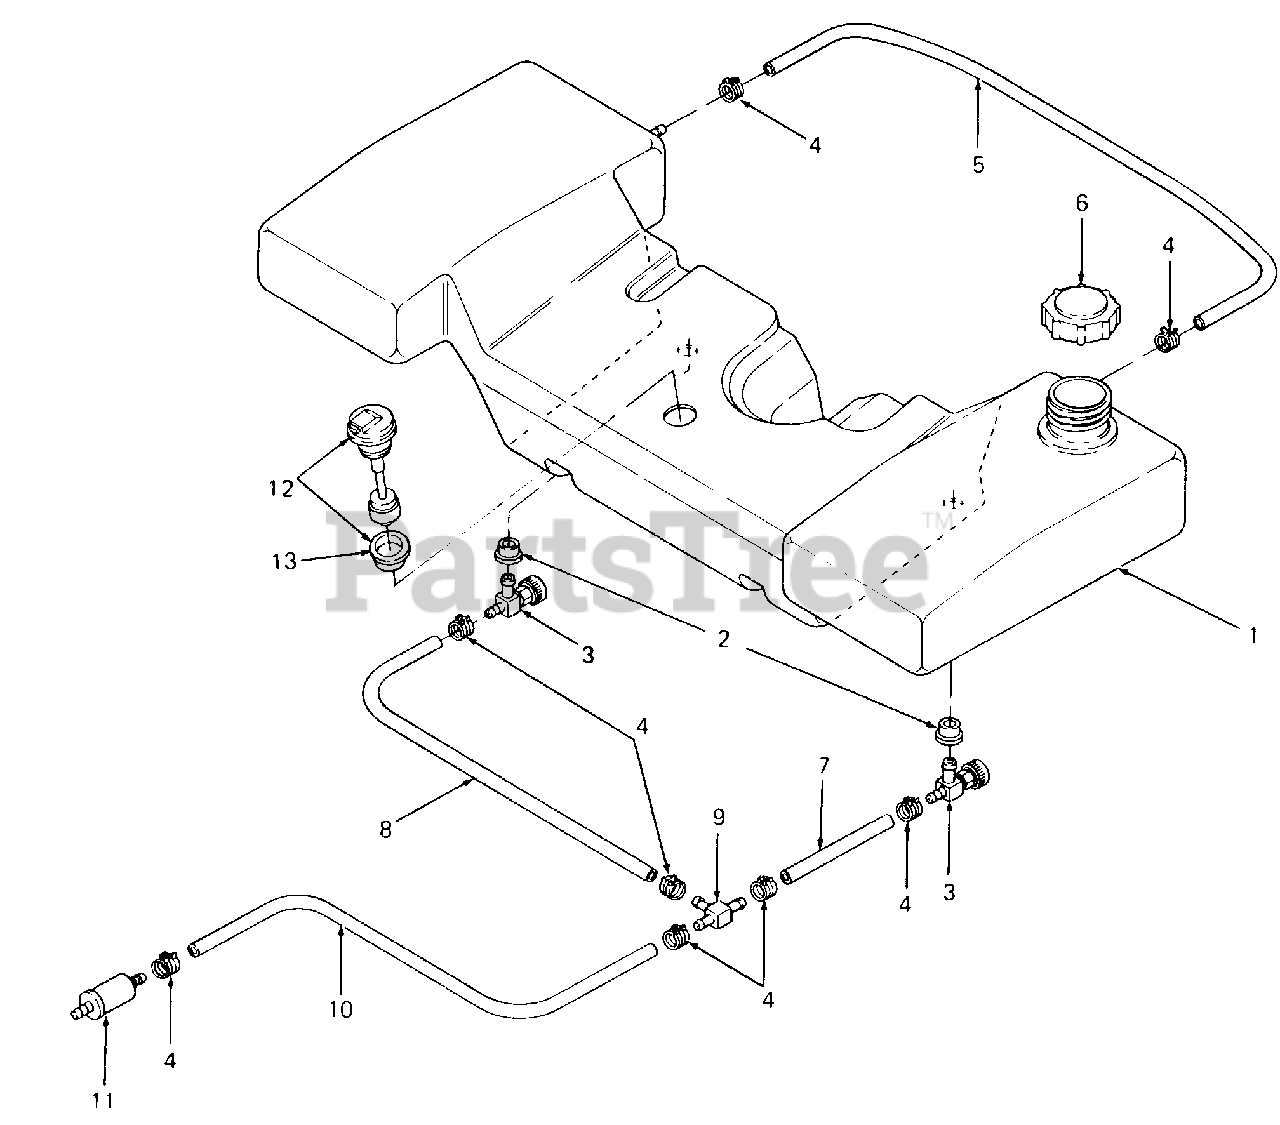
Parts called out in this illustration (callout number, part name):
1	Tank, Fuel
2	Bushing
3	Valve, Fuel Shutoff
4	Clamp, Hose
5	Line, Fuel -24" Lg
6	Cap, Fuel
7	Line, Fuel -5" Lg
8	Line, Fuel -17" Lg
9	T-Fitting
10	Line, Fuel -41" Lg
11	Filter, Fuel
12	Sensor, Low Fuel
13	Bushing, Rubber
